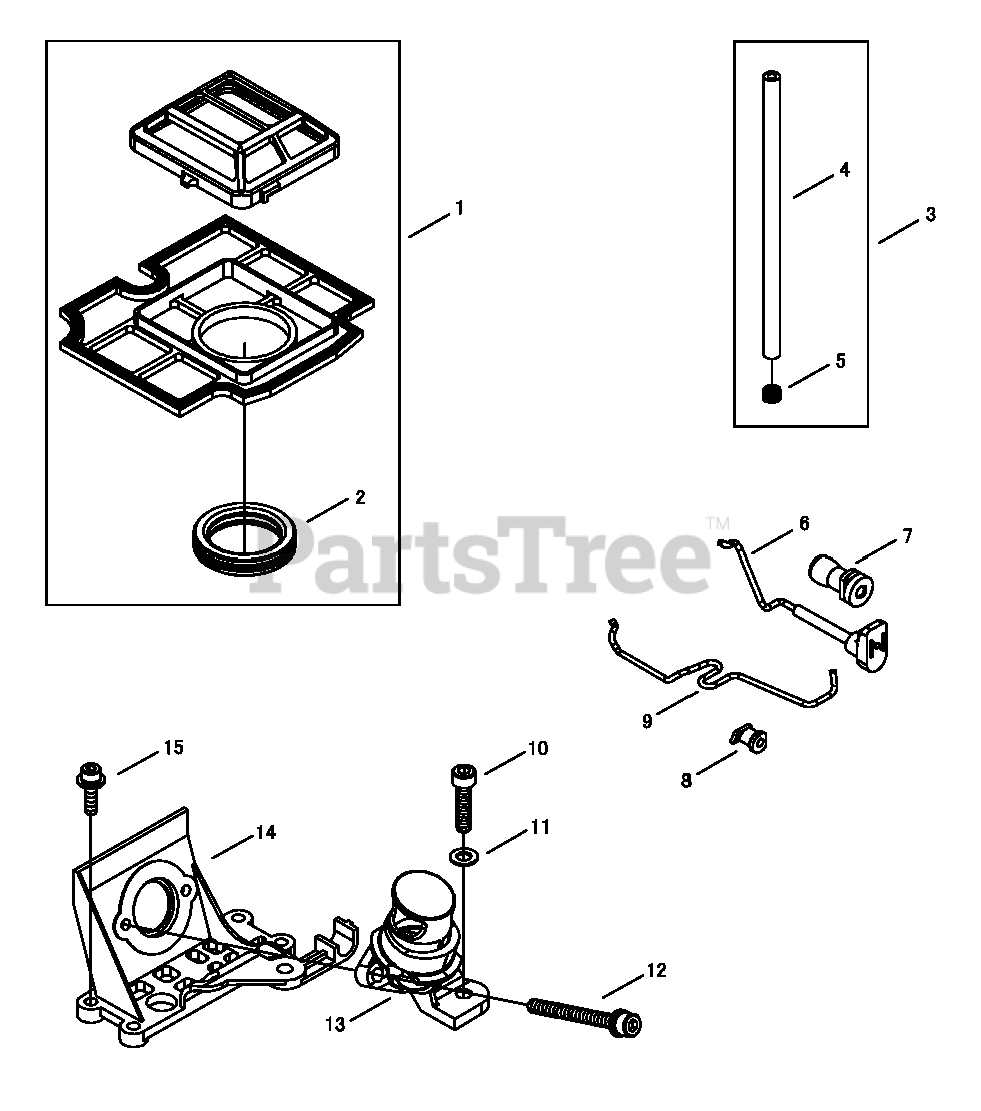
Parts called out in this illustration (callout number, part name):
1	AIR FILTER KIT
2	GROMMET
3	PULSE PIPE ASSY
4	PIPE - PULSE
5	CLIP - 5.7
6	ROD, CHOKE
7	GROMMET
8	GROMMET
9	ROD, THROTTLE
10	BOLT
11	WASHER - 5
12	BOLT
13	ADAPTOR, INTAKE
14	INSULATOR, INTAKE
15	SCREW - 4X16
